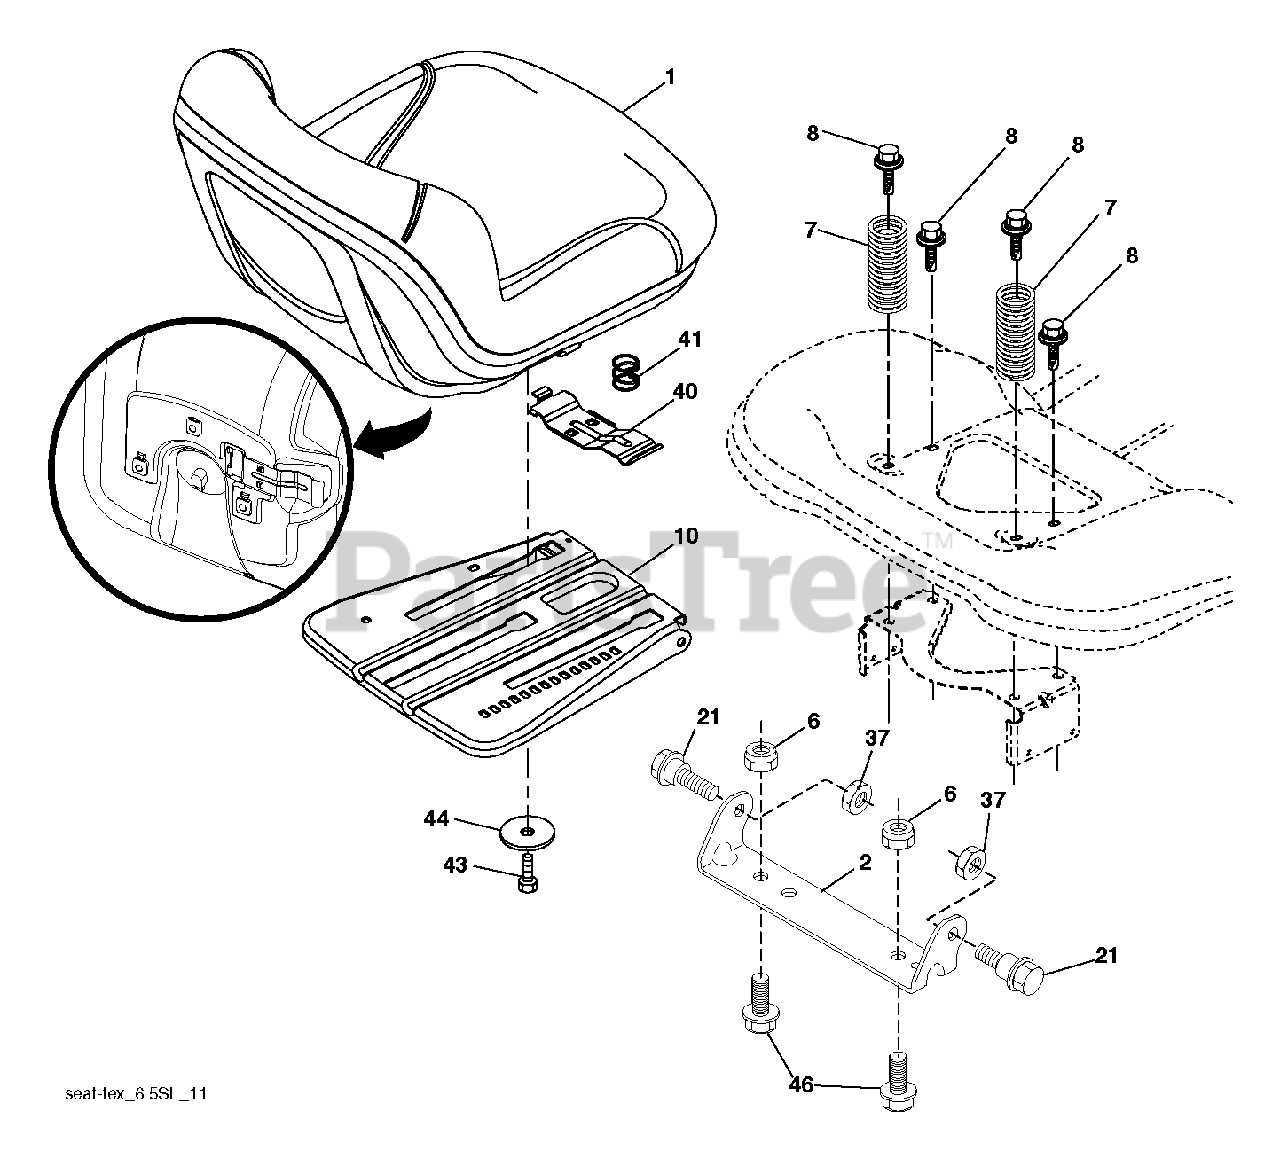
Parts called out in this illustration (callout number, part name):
1	SEAT.TH150.MS498.GRY.HUSQ.TEX
2	BRKT.PIVOT.FENDER
6	NUT
7	SPRING.COMPRESSION.SEAT.BLACK
8	BOLT, 5/16-18 X 1 3/4
10	PAN.ASM.SEAT.3PT
21	BOLT.5/16-18X5/8.SHOULDER
37	NUT.71038.31-18.HEX.NYLOCK
40	HANDLE.SLIDE.SEAT.TEX.GREY
41	SPRING.LATCH.SEAT.TEX
44	WASHER 13/32 X 2-3/8 X 12GA
46	BOLT.3/8-16X1;1.25OD.WSHR.SEMS
